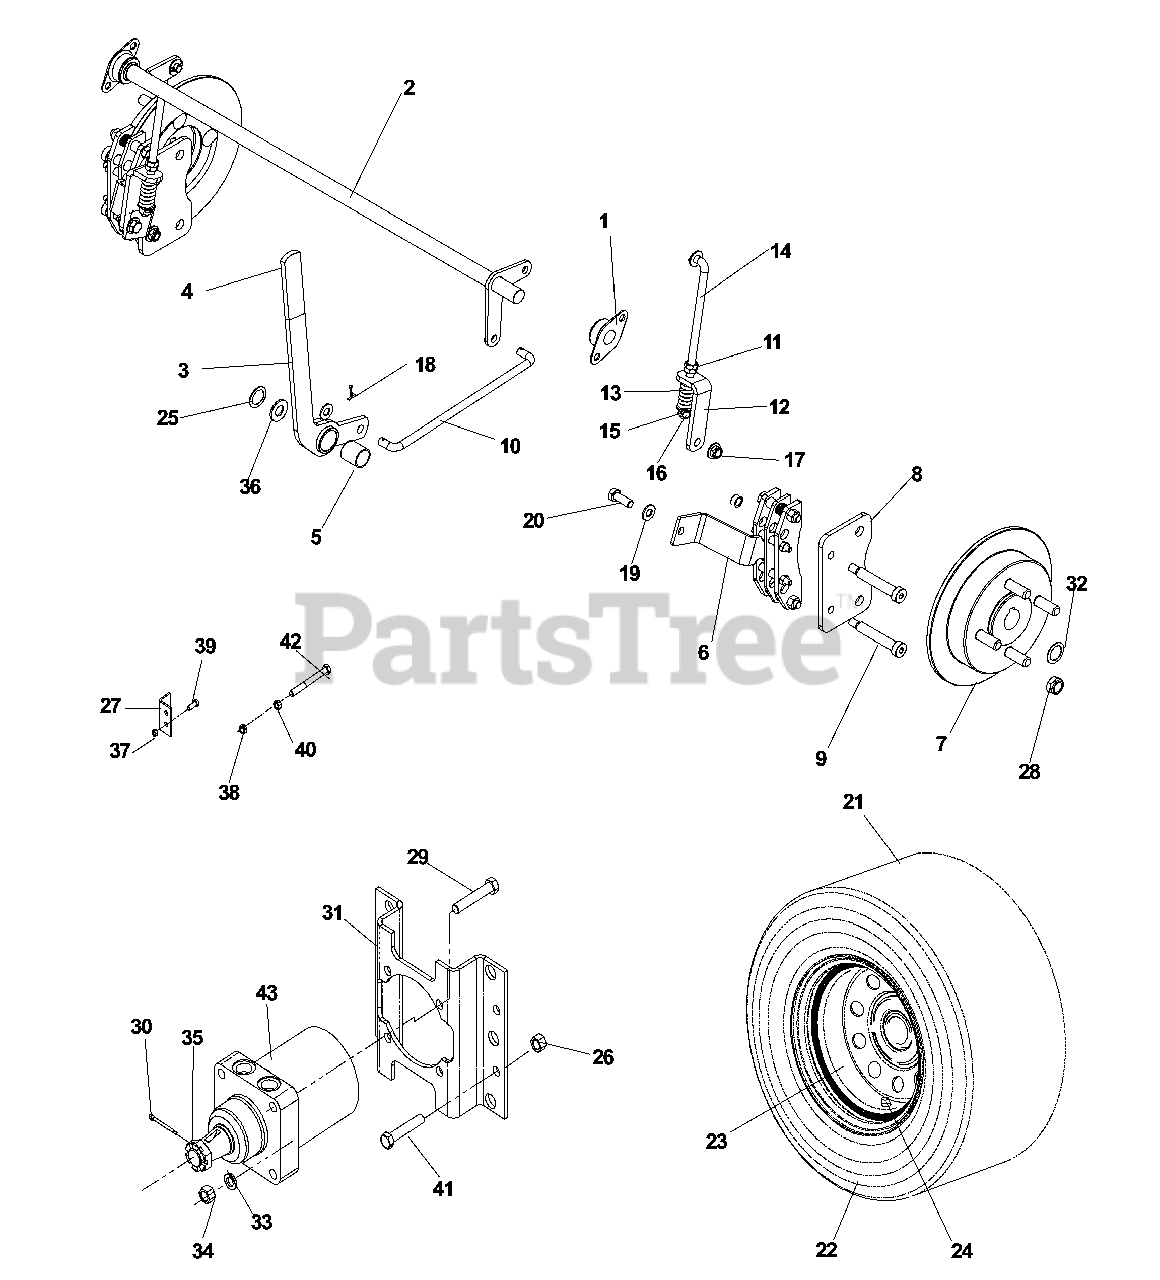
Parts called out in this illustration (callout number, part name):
1	FLANGE BEARING
2	BRAKE CROSS SHAFT
4	GRIP BRAKE HANDLE
5	BUSHING
6	CALIPER ASSEMBLY
8	PLATE, BRAKE
9	SB 3/8-16 X 2-1-1/2 SKT HDD ZD
10	LINKAGE, BRAKE
11	NUT 3/8-24 JAM
12	BRACKET, L
14	LINKAGE, REAR BRAKE
15	WASHER 3/8 SAE FLAT
16	NUT 3/8F CENTERLOCK
17	NUT HEX 3/8-16 NYLON, THIN
18	COTTER PIN 3/32 X 3/4
19	WASHER 3/8 SAE FLAT
20	HCS 3/8C X 1
24	VALVE STEM TR-412
25	RETAINING RING, 7/8"
26	NUT 1/2-13 HEX NYLOC ZD
27	BRACKET
28	LUG NUT 1/2F
29	HCS 1/2C X 2 3/4
30	PIN COTTER 4MM X 45MM
31	MOTOR STANDOFF
32	MACHINE BUSHING
33	WASHER 1/2" SPLIT LOCK
34	NUT HEX 1/2
35	NUT 3/4-16 HEX SLTD GR5 ZD
36	BSHG .875 X 1.375 X .074 ZD
37	NUT 1/4-20 NYLOC
38	NUT 3/8-16 NYLOC
39	HCS 1/4C X 3/4 HCS
40	NUT 3/8C WHIZ
41	HCS 1/2C X 1 1/4 SERRATED HEAD
42	HCS 3/8C X 2 1/2
43	WHEEL MOTOR, TJ
